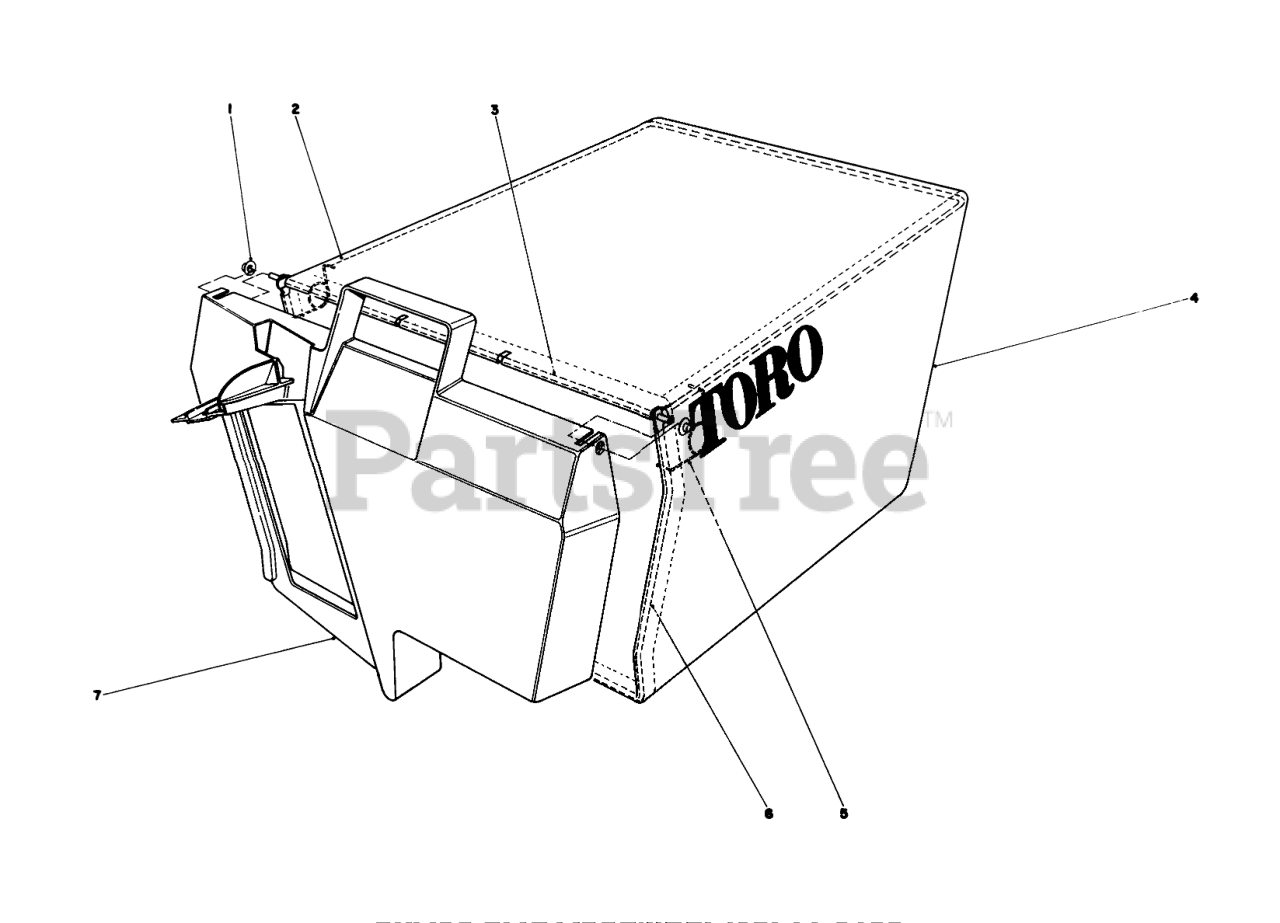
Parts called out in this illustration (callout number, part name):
1	NUT-PUSH
2	FRAME-BAG, UPPER
3	HINGE-DOOR, BAG
4	Bag
5	SPRING
6	CABLE-BATTERY TO SOLENOID
7	Door Grass Bag
